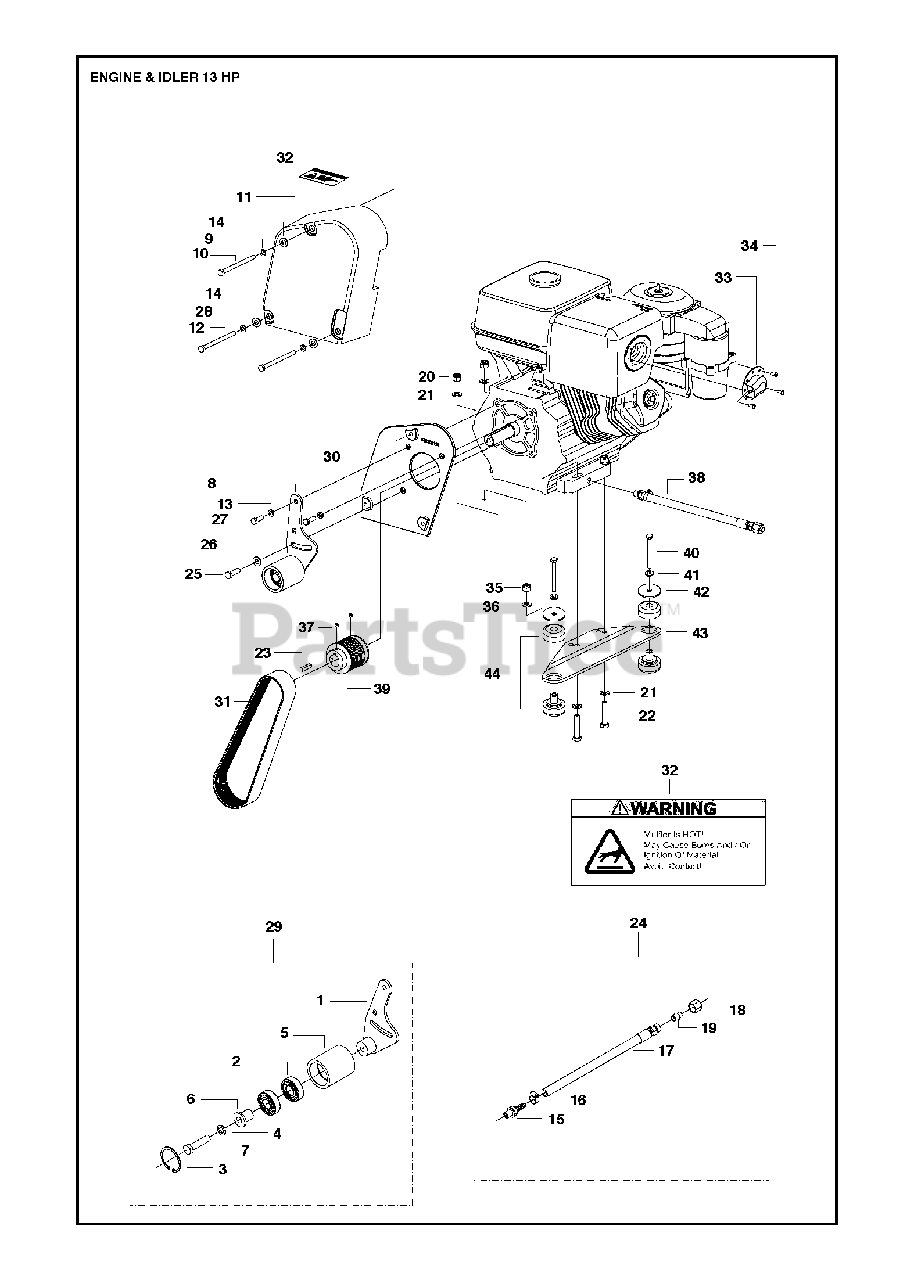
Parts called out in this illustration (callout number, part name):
8	IDLER SHEAVE ASSEMBLY
9	SPRING WASHER
13	SPRING WASHER
14	WASHER
16	CLAMP, HOSE, MAH-4 FUEL LINE
20	HEXAGON LOCKING NUT
21	WASHER
28	SPRING WASHER
29	IDLER SHEAVE ASSEMBLY
30	BELT GRD PLATE TRIM-PC H.GREY
35	HEXAGON LOCKING NUT
36	WASHER
39	SHEAVE PK.67MM.25.4MM.12G.B/O
